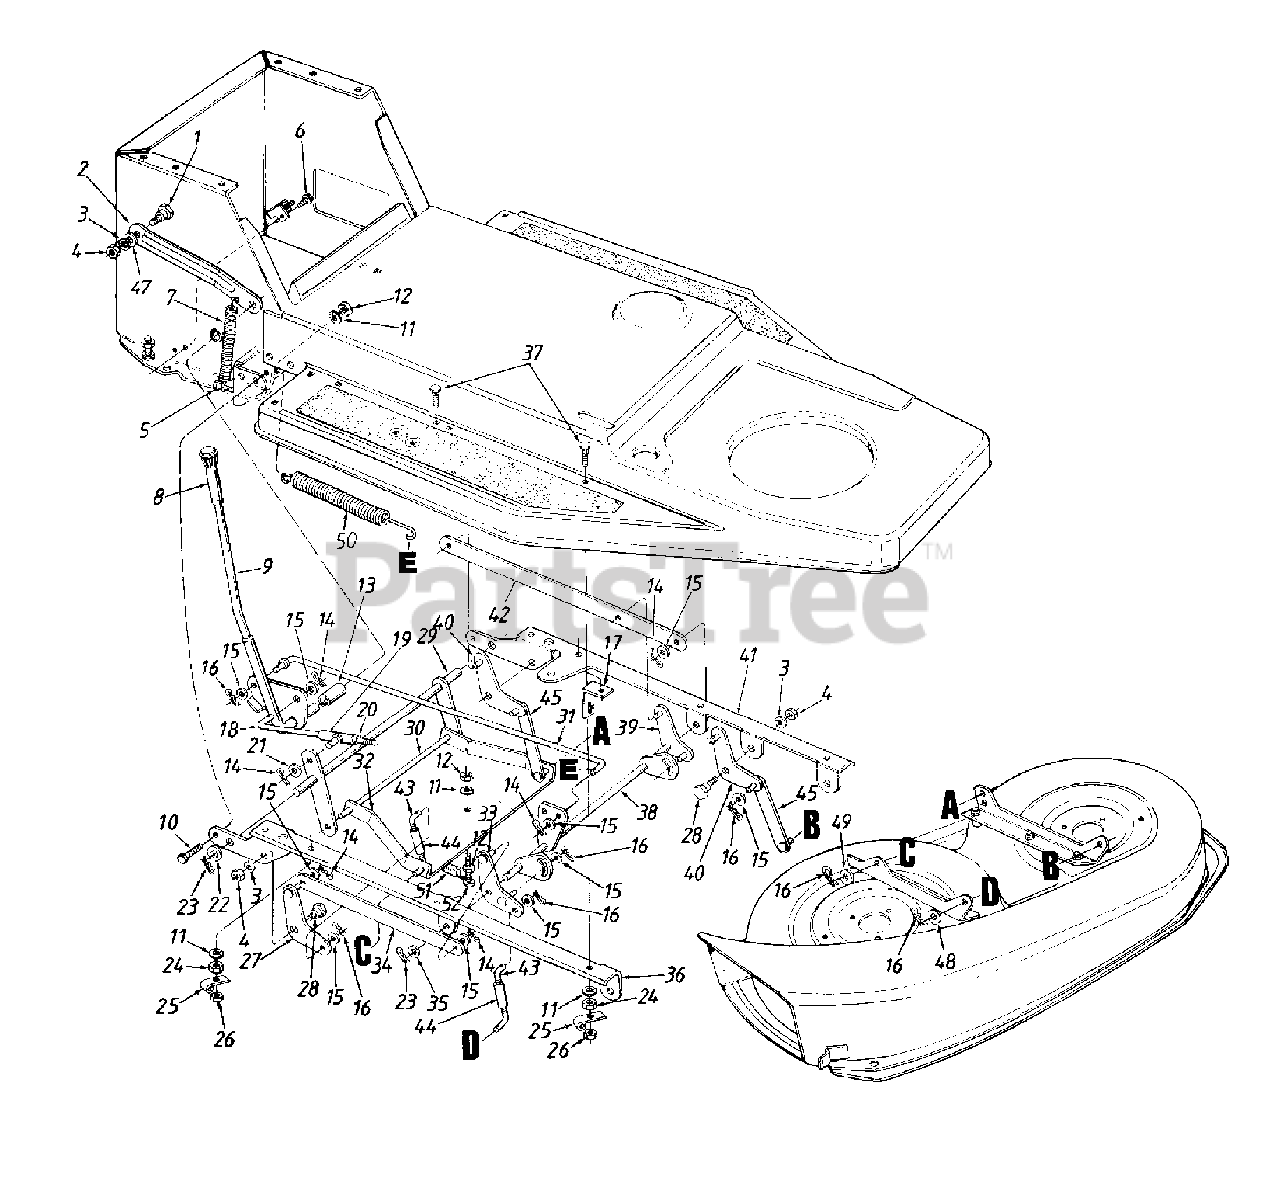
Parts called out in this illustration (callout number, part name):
1	Shoulder Bolt .5" Dia. x .34" Lg.
4	Hex Nut 3/8-16 Thd.
5	Hex Bolt 1/4-28 x 1.25" Lg.
6	Hex TT-Tap Scr. 1/4-20 x .5" Lg.
7	External Spring
8	Grip
9	Deck Lift Handle Ass'y.
10	Hex Washer TT-Tap Scr.
11	Lock Washer 5/16" I.D.
12	Hex Nut 5/16-18 Thd.
13	Spacer 5/8" I.D. x .78"
14	Cotter Pin 3/32" Dia. x .75" Lg.
15	Flat Washer .406" I.D. x .75" O.D.
16	Internal Cotter Pin 5/16" Dia.
19	Pivot Sleeve Ass'y.
20	Hex Lock Nut 3/8-16 Thd.
21	Thrust Washer .382" I.D.
22	Flat Washer .635" I.D. x .93" O.D.
23	Cotter Pin 1/8 Dia. x 1.25" Lg.
24	Hex Nut 5/16-24 Thd.
25	Harness Retainer
26	Hex Cent. Lock Nut 5/16-24 Thd.
27	Deck Pivot Brkt. Ass'y.-R.H.
28	Shld. Bolt .625" Dia. x .170" Lg.
31	Deck Lift Rod
44	Adj. Lift Link Ass'y.
45	Deck Lift Link Ass'y.
47	Flat Washer .531" I.D. x .94"
48	Flat Washer .406" I.D. x .75"
49	Flat Washer 3/8" I.D.
50	Ext. Spring .87" Dia.
51	Ext. Spring 11" Lg.
52	Hex Bolt 5/16-18 x 7/8" Lg.
